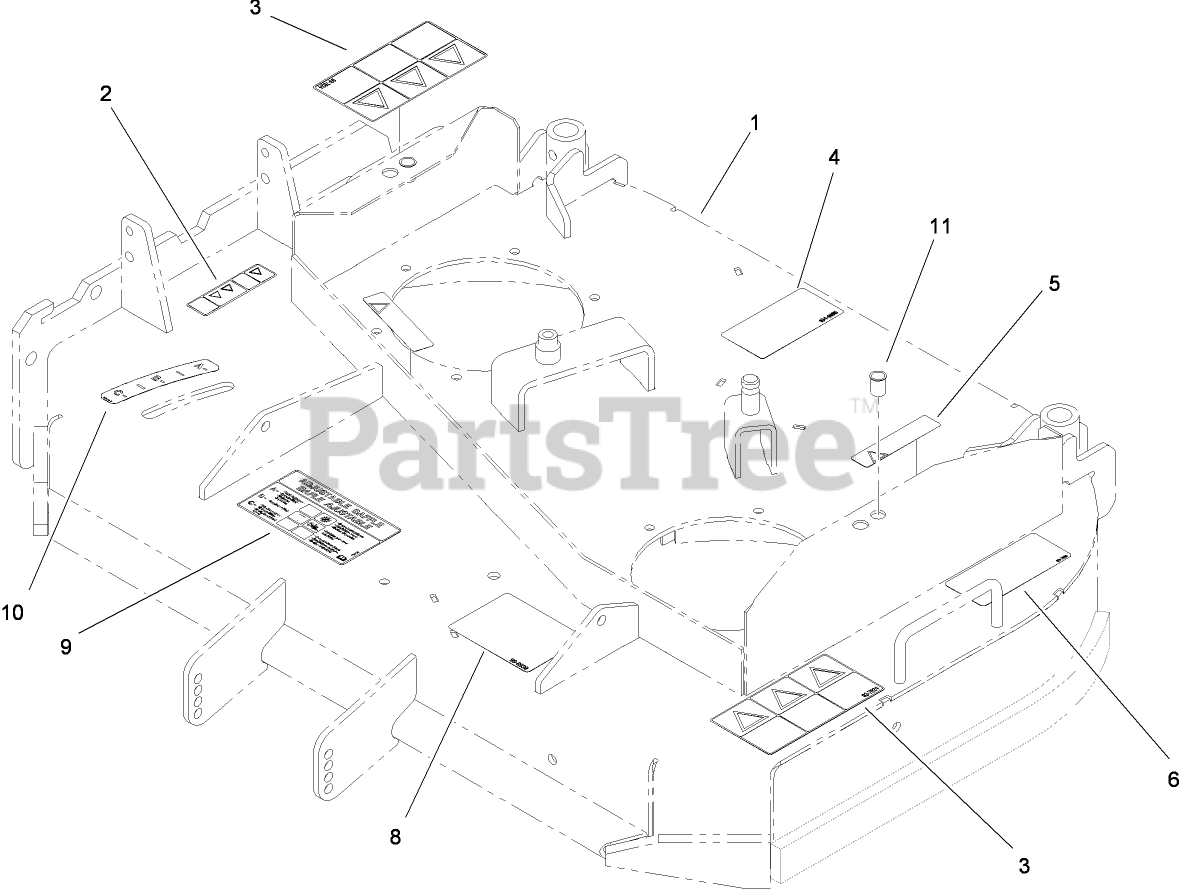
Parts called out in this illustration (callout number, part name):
1	Deck ASM
2	DECAL-WARNING, DEFLECTOR
3	DECAL-DANGER
5	DECAL-WARNING
6	DECAL-TORQUE, BLADE BOLT
8	DECAL-ANTI SCALP
9	DECAL-ADJUSTMENT, BAFFLE
10	DECAL-SETTING, BAFFLE
11	INSERT-NUT
